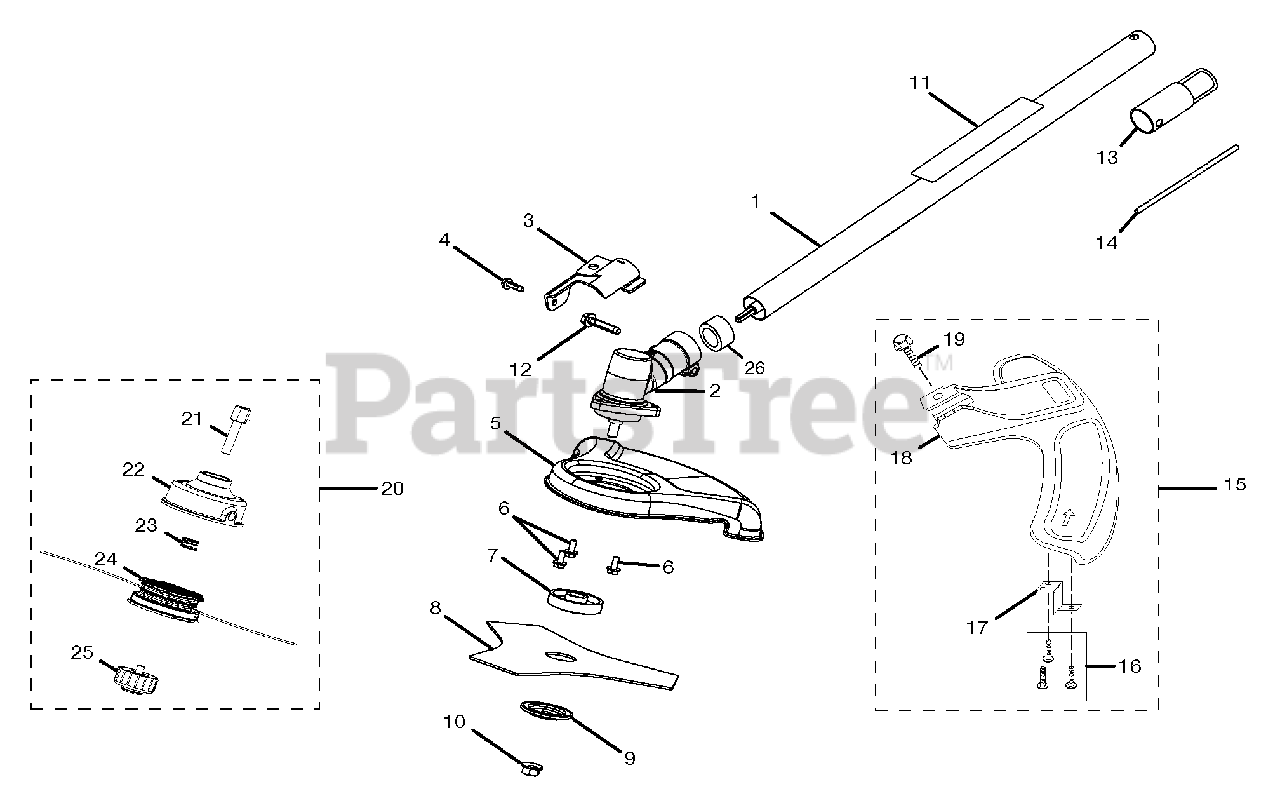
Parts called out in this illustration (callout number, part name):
1	Straight Shaft Assembly
2	Gear Case Assembly
3	Grass Deflector Clamp
4	Screw(#10-24 x 5/8 in. Hex Washer Head, Tri-Lobular)
5	Brushcutter Guard
6	Screw (#10-24 x 1/2 in., Sems Slotted Hex Head)
7	Flanged Washer
8	Blade (Tri-Arc(TM))
9	Cupped Washer
10	Blade Nut,Left-handed threads
11	Warning Label
12	Screw(#1/4-20 x 1-1/4 in. Hex Washer Hd., Mach.)
13	Storage Cap
14	Head Locking Tool
15	Grass Deflector Assembly
17	Line Cutting Blade
18	Grass Deflector
19	Screw(#1/4-20 x 1-1/4 in. Hex Washer Hd., Mach.)
20	Trimmer Head Assembly
21	Trimmer Head Shaft Adaptor
22	Trimmer Head
23	Compression Spring
24	Spool with Line (.095)
25	Retaining Cap, Left-handed Thread
26	Spacer
